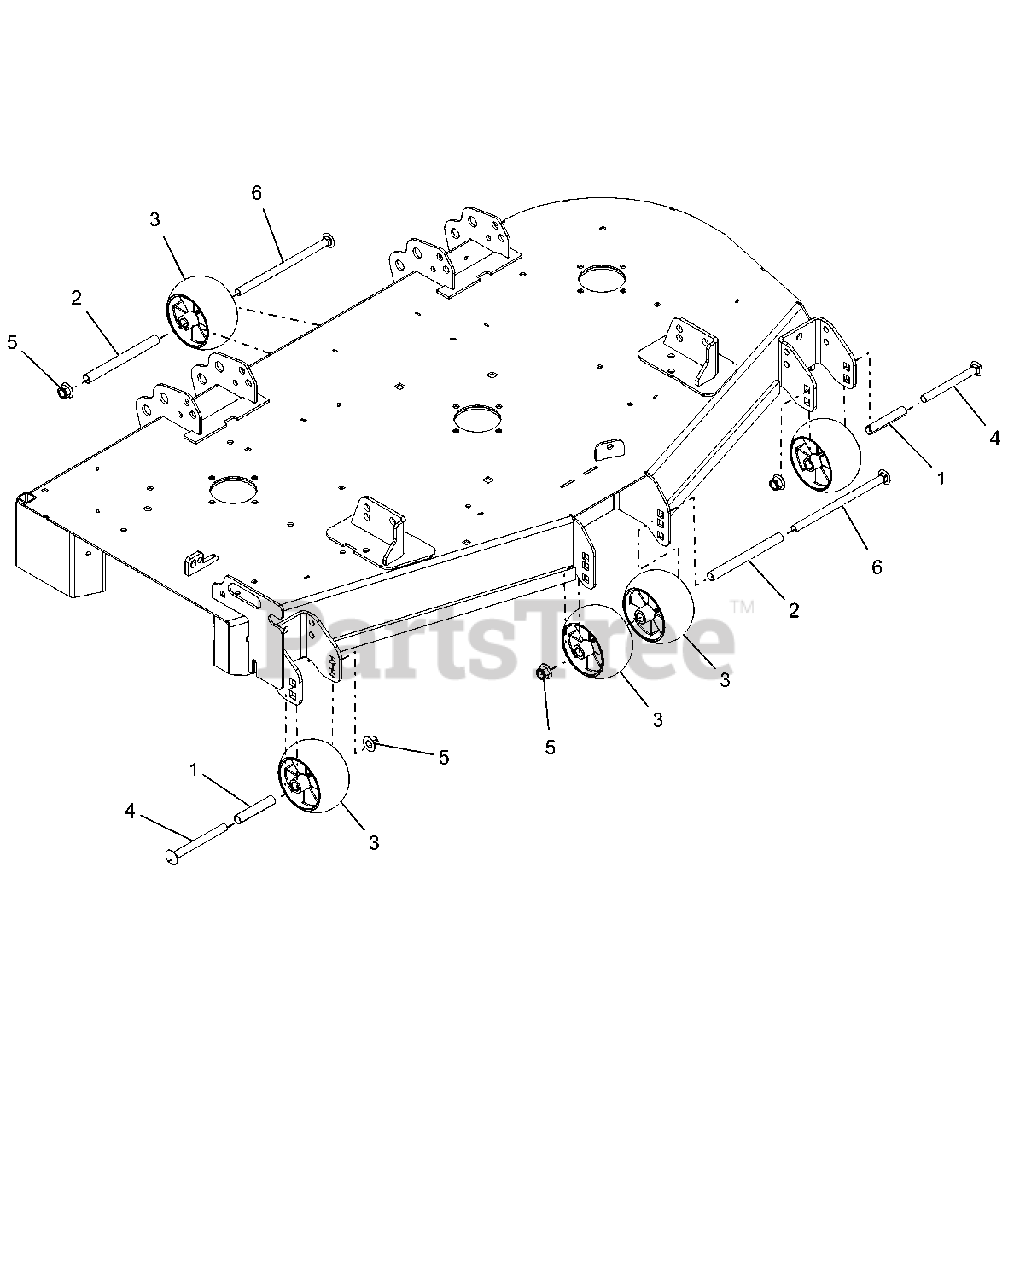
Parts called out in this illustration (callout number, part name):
1	SPACER, .510X.625X3.35
2	SPACER, .510X.625X6.50
3	ANTI-SCALP WHEEL - 5X3 CTR
4	BLT-RDHDSQNK .50-13X5.00 GR5YZ
5	@NUT-LK-NYL-FLG .50-13 YWZC
6	@BLT-RDHDSQNK .50-13X8.50 G5YZ
